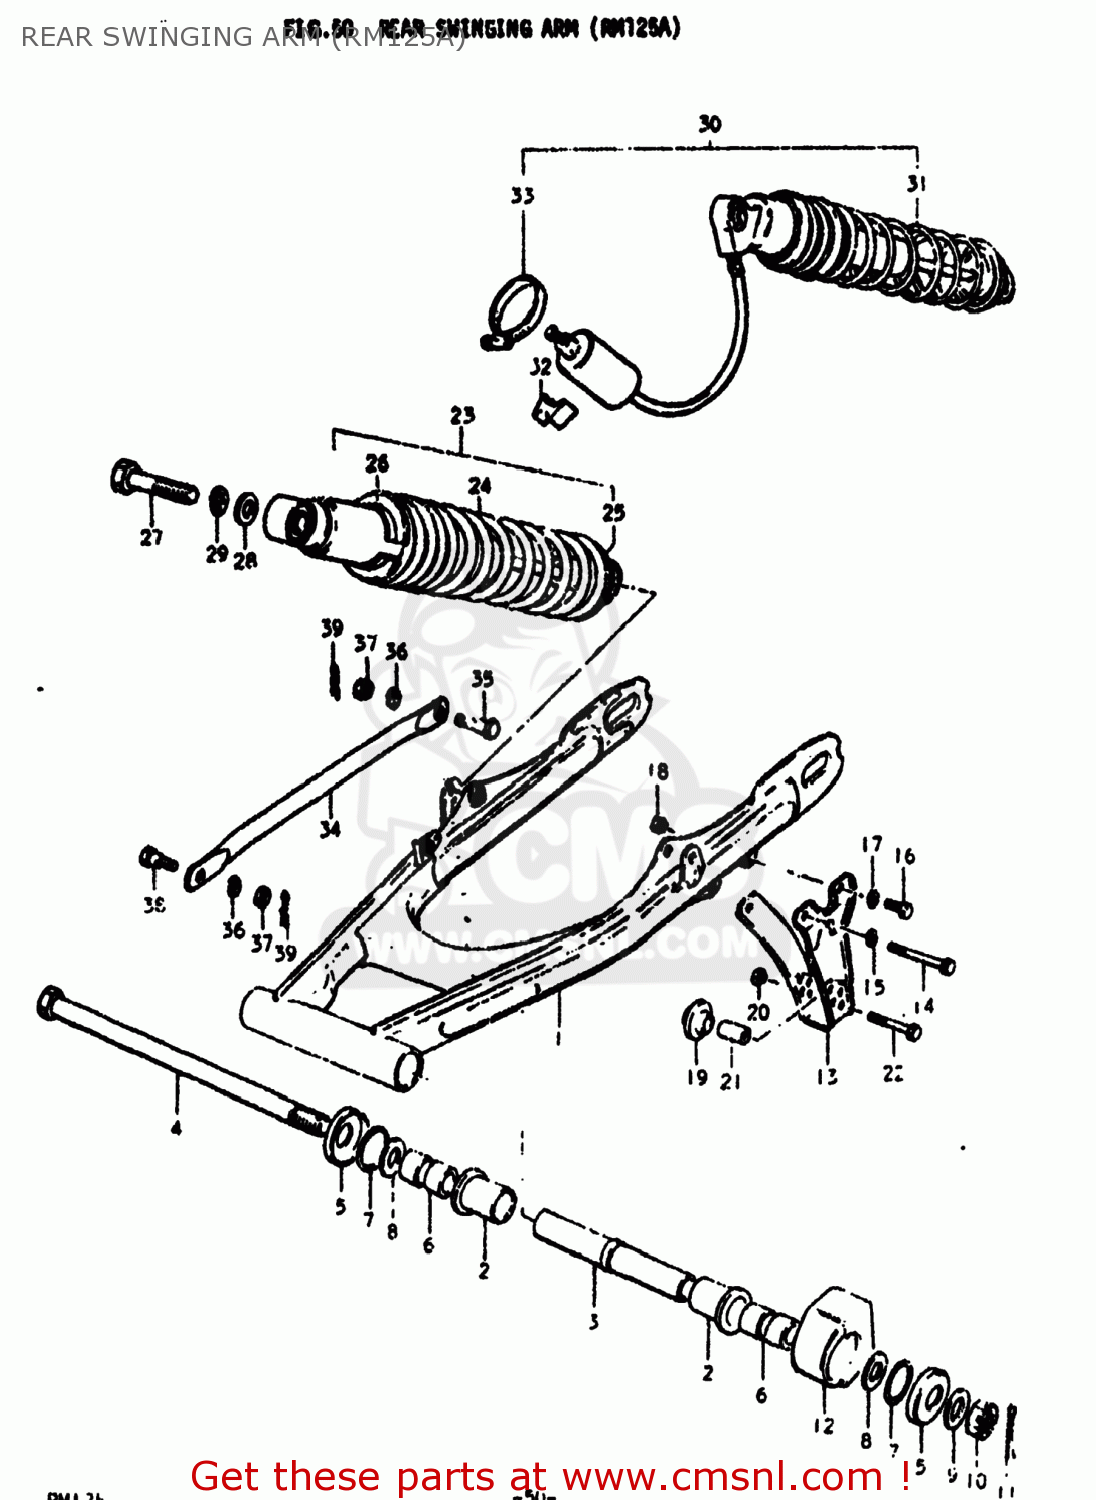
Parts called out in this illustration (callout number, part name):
1	SWING ARM ASSEMBLY,REAR
2	BUSH
3	SPACER,SWING ARM,CENTER
4	SHAFT,REAR SWING ARM
5	COVER,SWGARM BUSH DUST SEAL
6	SPACER,RR SWGARM PIVOT
7	O RING(D:2,ID:24.5)
8	WASHER(12.5X24X2.3)
9	WASHER
10	NUT, REAR AXLE
11	PIN 30X20
12	BUFFER,CHAIN TOUCH DEFLECTOR
13	GUIDE,CHAIN
14	BOLT
15	LOCK WASHER
16	BOLT
17	LOCK WASHER
18	NUT
19	RUBBER,CHAIN GUARD
20	NUT (6MM)
21	SPACER(6.5X10.5X22.5)
22	BOLT
23	ABSORBER ASSEMBLY,REAR SHOCK
24	SPRING
26	GUIDE,SPRING
27	BOLT 10X40
28	WASHER
29	LOCK WASHER
30	ABSORBER ASSEMBLY,REAR SHOCK
31	ABSORBER ASSEMBLY,REAR SHOCK
32	CUSHION,RR SHOCK ABSORBER
33	CLAMP
34	TORQUE LINK,REAR
35	BOLT(8X26.5)
36	LOCK WASHER
37	NUT
38	BOLT(8X22)
39	CLIP
